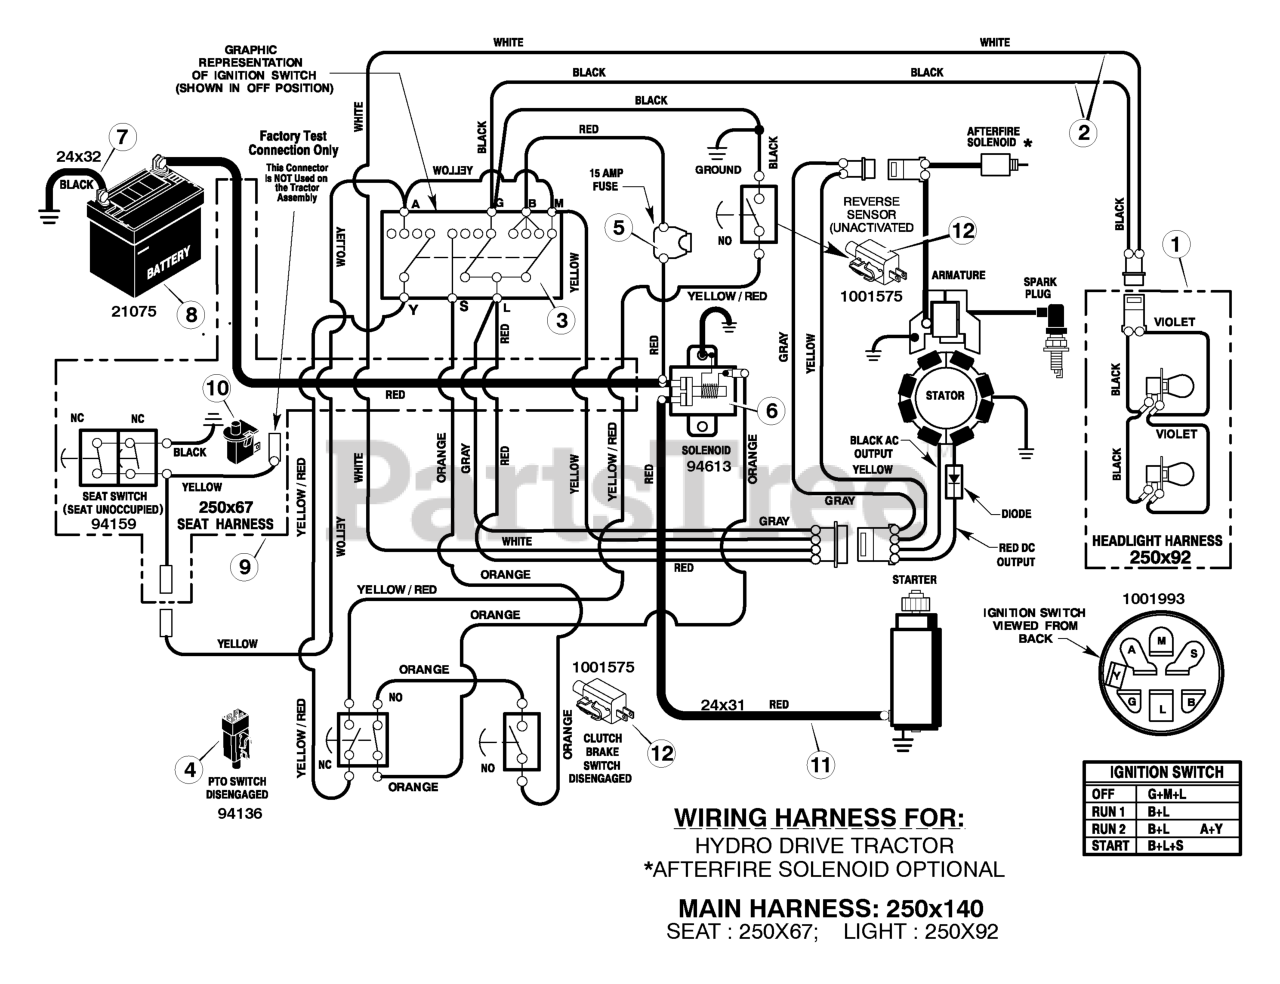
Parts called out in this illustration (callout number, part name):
1	Harness, Light Wire
2	Harness, Chassis Wire
3	Switch, Ignition
4	Switch, Limit (PTO)
6	Solenoid
7	Cable, Battery Ground
8	Battery
9	Harness, Seat Switch Wire
10	Switch, Seat Sensor
12	Switch, Select Reverse / Clutch Brake
